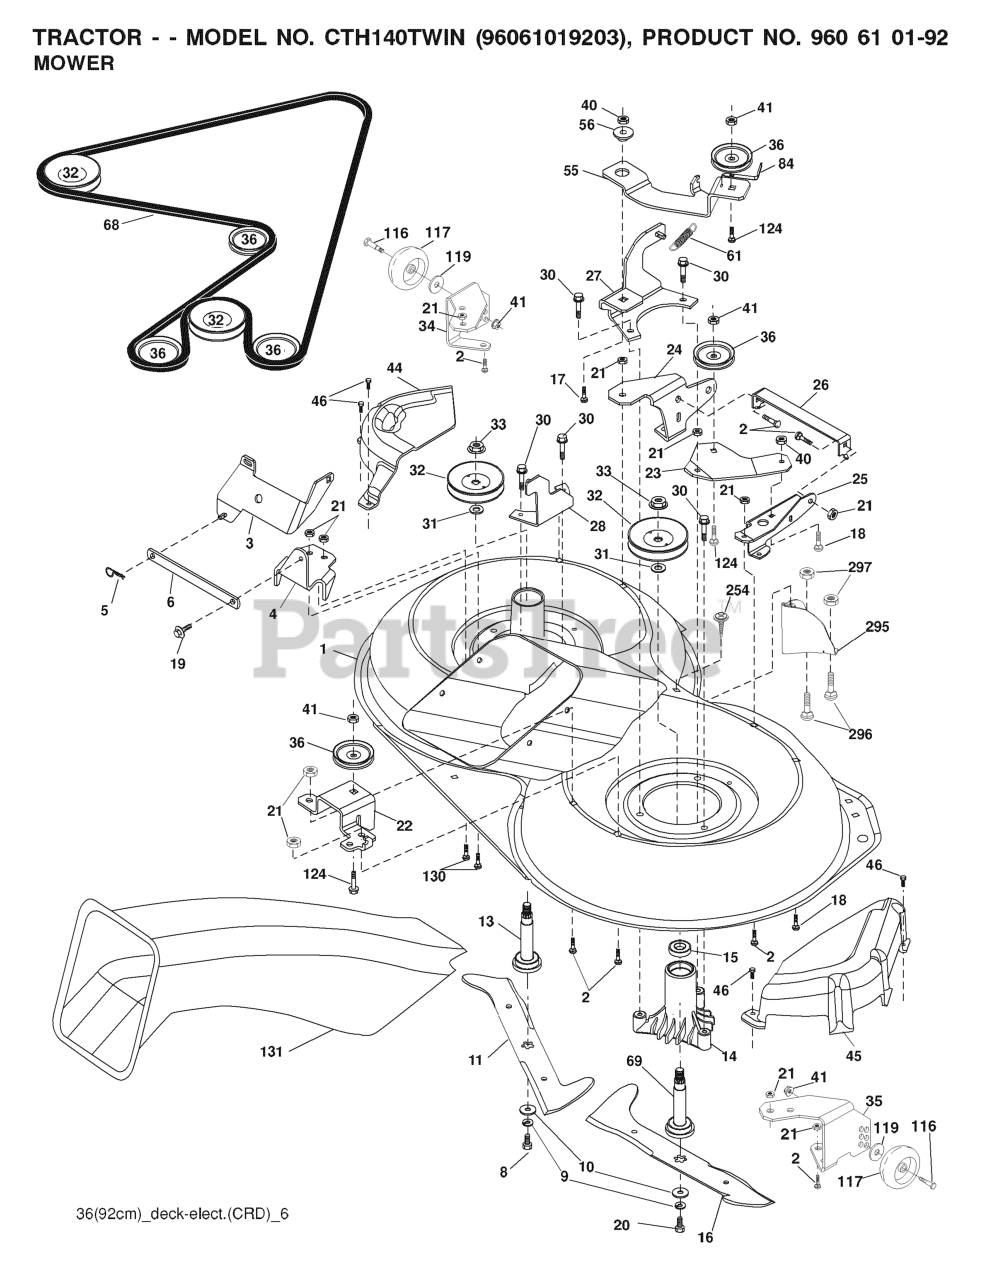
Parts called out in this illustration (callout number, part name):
2	RP BOLT 5/16-18 X3/4 ZN/YEL GR
5	RETAINER-SPRNG RB
6	BAR.SWAY.92.CRD
8	BOLT.3/8-24X1.25 GR8
9	LOCKWASHER
10	WASHER.BLADE
13	SHAFT ASM VENT
14	HOUSING.MANDREL.VENTED (MACHD)
17	BOLT.3/8-14X1.25
19	BOLT SHD 5/16-18
20	BOLT.3/8-24X1.25GR8. LHTHRD
21	LOCKNUT
26	SUPPORT
30	SCREW, WASHER HEAD
31	WASHER.SPACER.MANDREL
32	PULLEY MANDREL
33	NUT.FLANGE.LOCK.TOP
36	PULLEY.IDLER.4.25
41	NUT LOCK FLG 3/8-16 UNC
45	COVER.MANDREL.RH.CRD
46	SCREW.1/4-20X5/8
55	ARM.IDLER.92 CRD.2006
56	SPACER.RETAINER.MOWER
61	SPRING
68	BELT.DRIVE.92CM.CRD.2006
69	SHAFT.ASM.W/LWR.BRG.RH.THREAD
84	KEEPER, BELT IDLER
116	BOLT.SHOULDER.3/8-16X3-5/8.
117	RP WHEEL. GUAGE RALLY
119	WASHER
124	BOLT.3/8-16X1.50
130	BOLT.CARR.SQNK.5/16-18UNC.X3/4
131	CHUTE BAGGER
254	SCREW 3/8-16X1
296	BOLT
297	NUT CENTERLOCK
